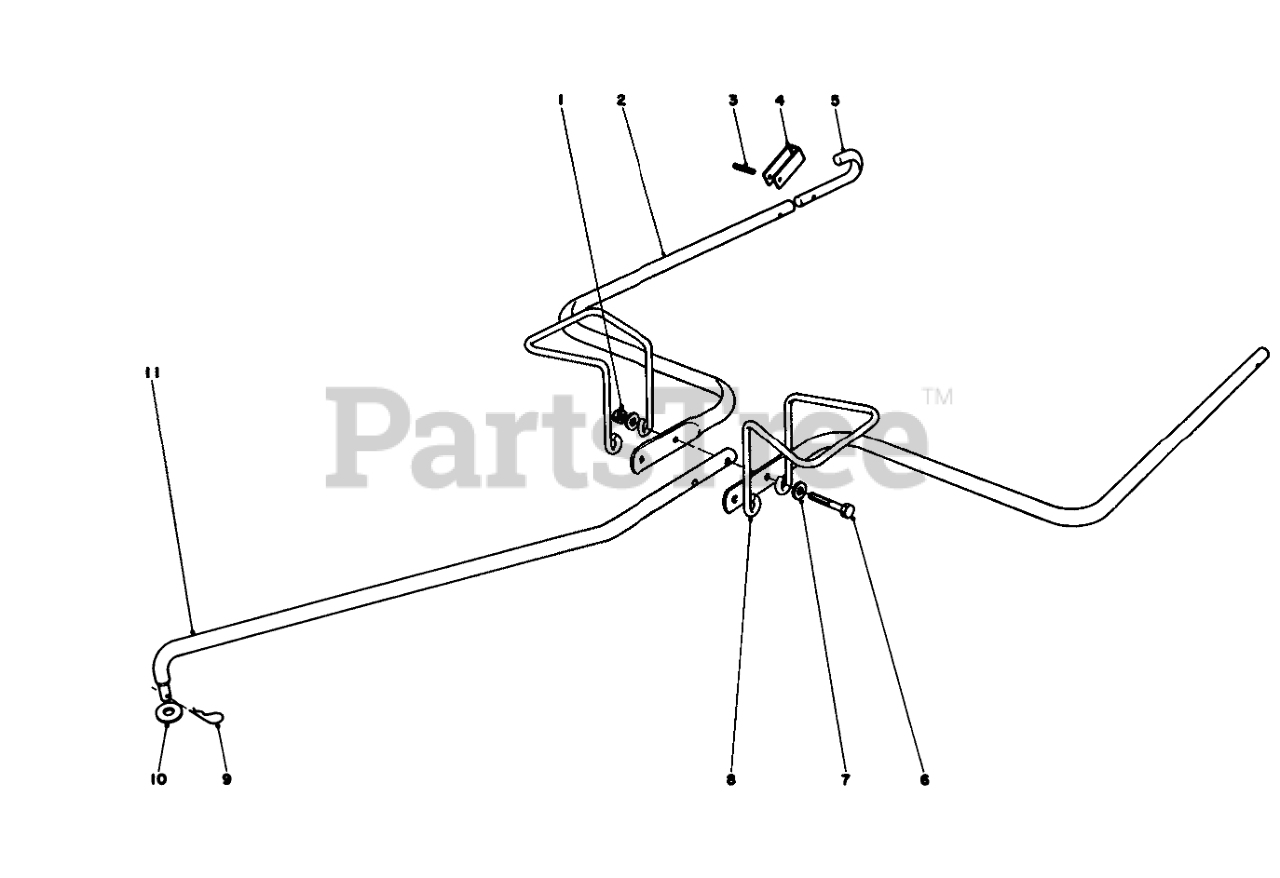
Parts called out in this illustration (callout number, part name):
1	NUT-LOCK, CONE
2	HITCH ARM
3	PIN-ROLL, SLOT
4	HITCH LOCK
5	HOOK HITCH ARM
6	SCREW-HH
7	WASHER-FLAT
8	Support Bag
9	PIN-COTTER
10	PUSH NUT
11	POLE HITCH
